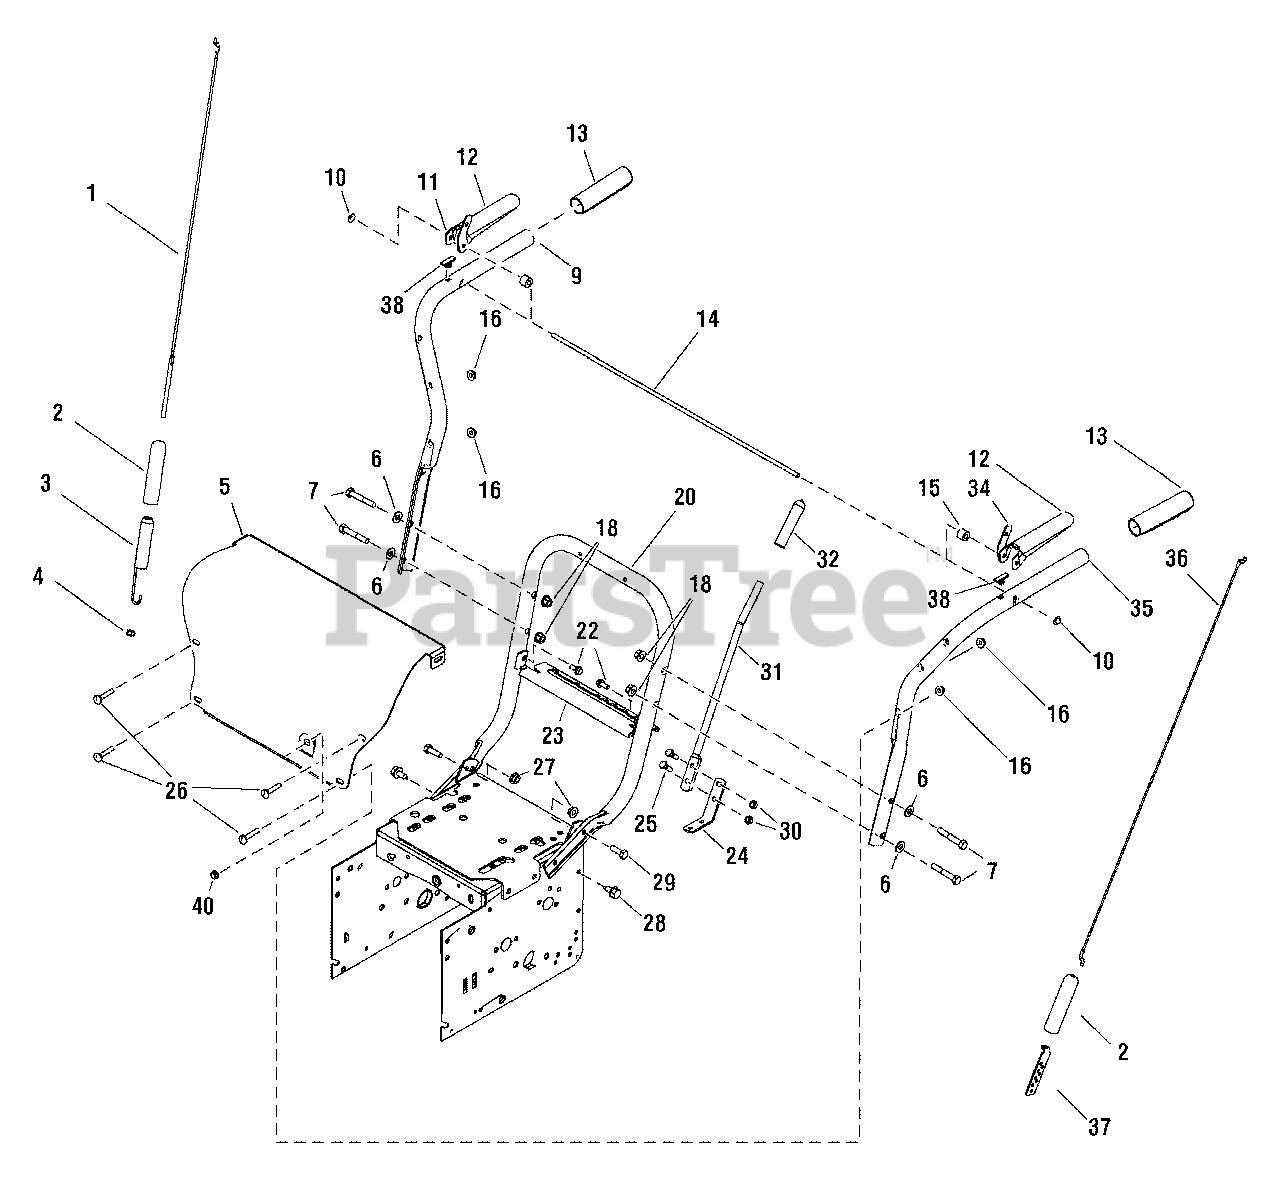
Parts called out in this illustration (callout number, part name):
1	CABLE, Auger
2	BOOT, Spring End Cover
3	SPRING, Auger Control
4	NUT, Hex Lock Esna Light 1/4-20
5	PANEL, Dash Upper
6	WASHER, 5/16
7	CAPSCREW, Hex Head 5/16-18 x 2 G5
9	HANDLE, Upper
10	NUT, Push Pal 1/4 Diameter Stud Capped
11	LEVER ASSEMBLY, Clutch R.H.
12	GRIP, Control Lever
13	GRIP, Handle
14	ROD, 1/4 Diamter 21.81 Large
15	SPACER
16	NUT, Hex Flange 1/4-20 Esna
18	NUT, Hex Flange 5/16-18 Esna
20	HANDLE, Lower
22	SCREW, Hex Washer Head Taptite 1/4-20 x 5/8
23	BRACKET, Gear Select
24	LEVER, Spring Shift
25	CAPSCREW, Hex Head 1/4-20 x 3/4 G5
26	CARRIAGE BOLT, 1/4-20 x 1-1/2 G5
27	NUT, Hex Flange 5/16-18 Two-Way Lock
28	SCREW, Hex Washer Head Taptite 5/16-18 x 3/4
29	CAPSCREW, Hex Head 5/16-18 x 1 G5
30	NUT, Hex Centerlock 1/4-20
31	ROD, Shift No Thread
32	GRIP, Ball End
34	LEVER ASSEMBLY, Clutch L.H.
35	HANDLE, Upper L.H.
36	CABLE, Front Drive
37	BRACKET, Cable Adjusting
38	BUMPER
40	BUSHING
